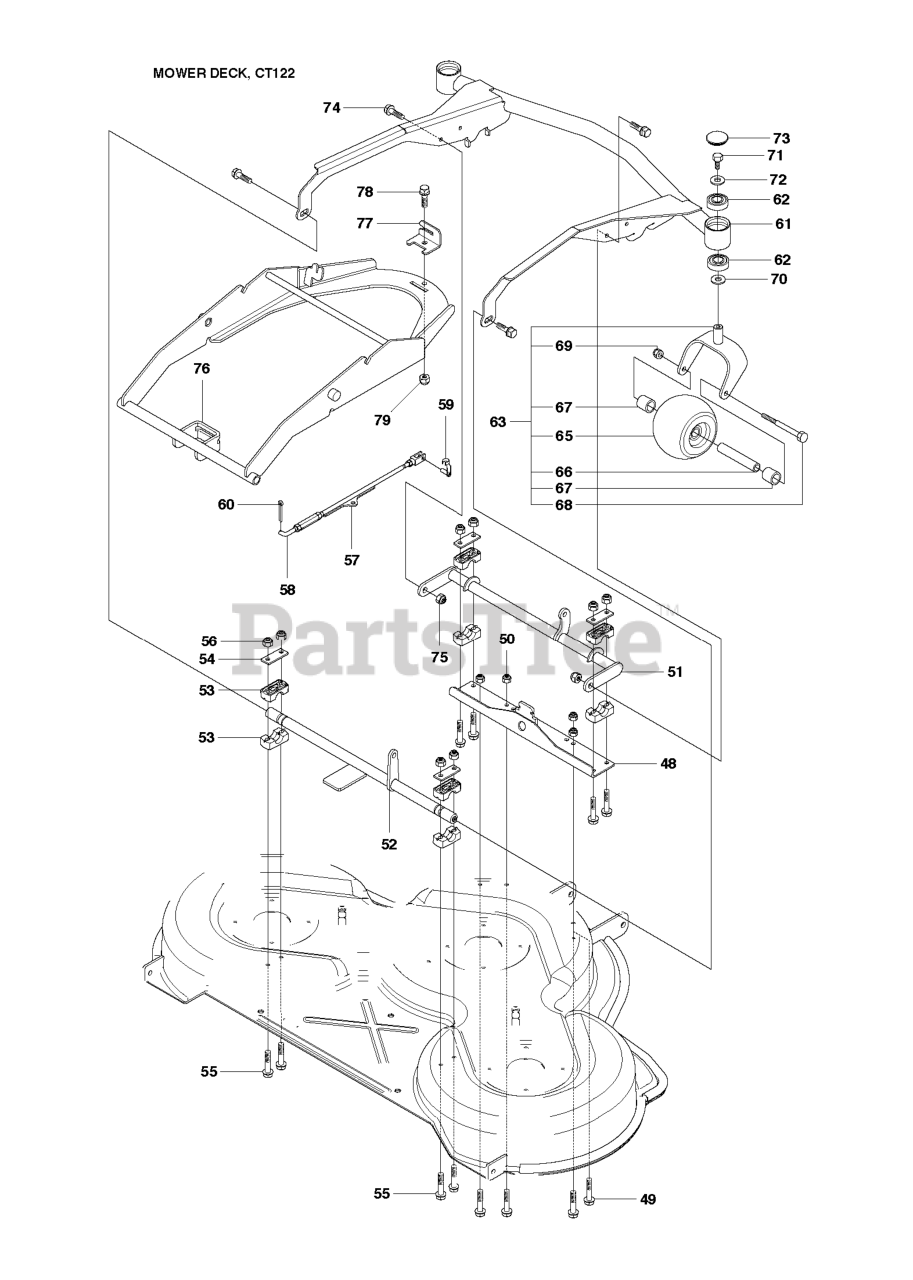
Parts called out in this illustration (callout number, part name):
50	LOCKNUT M8
56	LOCKNUT M8
58	PARALLEL ROD
62	BALL BEARING 6004-2RS1
63	PIVOT WHEELS
65	DECK ROLLER, FRONT
69	NUT
73	HUB CAP PIVOT WHEEL
75	LOCKNUT M8
79	LOCKNUT M8
